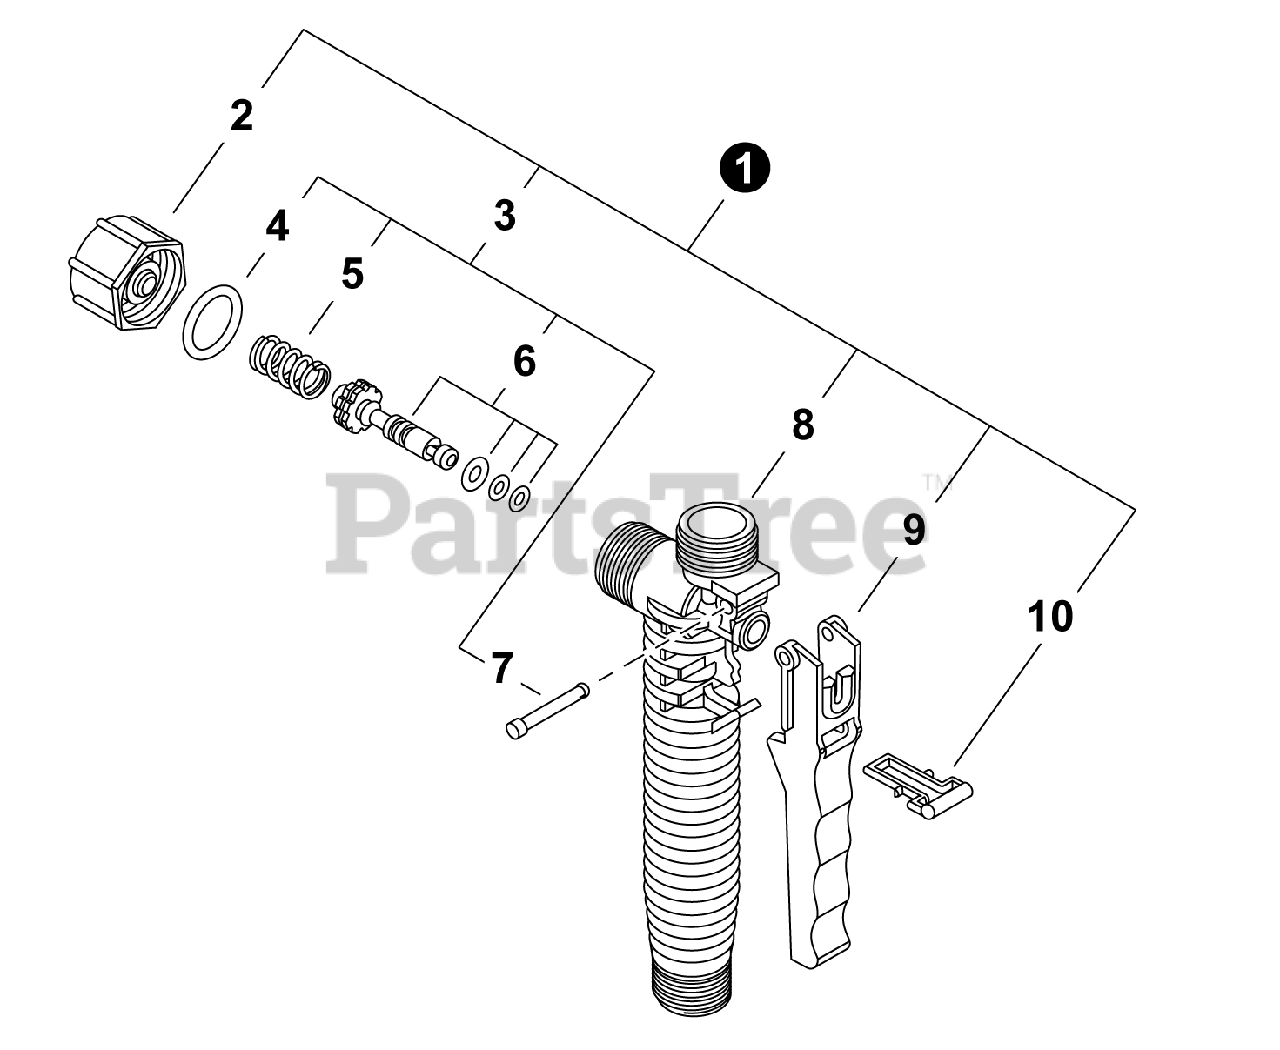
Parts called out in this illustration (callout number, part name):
1	GUN, SPRAY
2	CAP, DISCHARGE
3	REPAIR KIT, DISCHARGE
4	O-RING, DISCHARGE
5	SPRING, DISCHARGE
6	SPOOL ASSY
7	PIN, TRIGGER
8	BODY, SPRAY GUN
9	LEVER, TRIGGER
10	LOCK, TRIGGER
